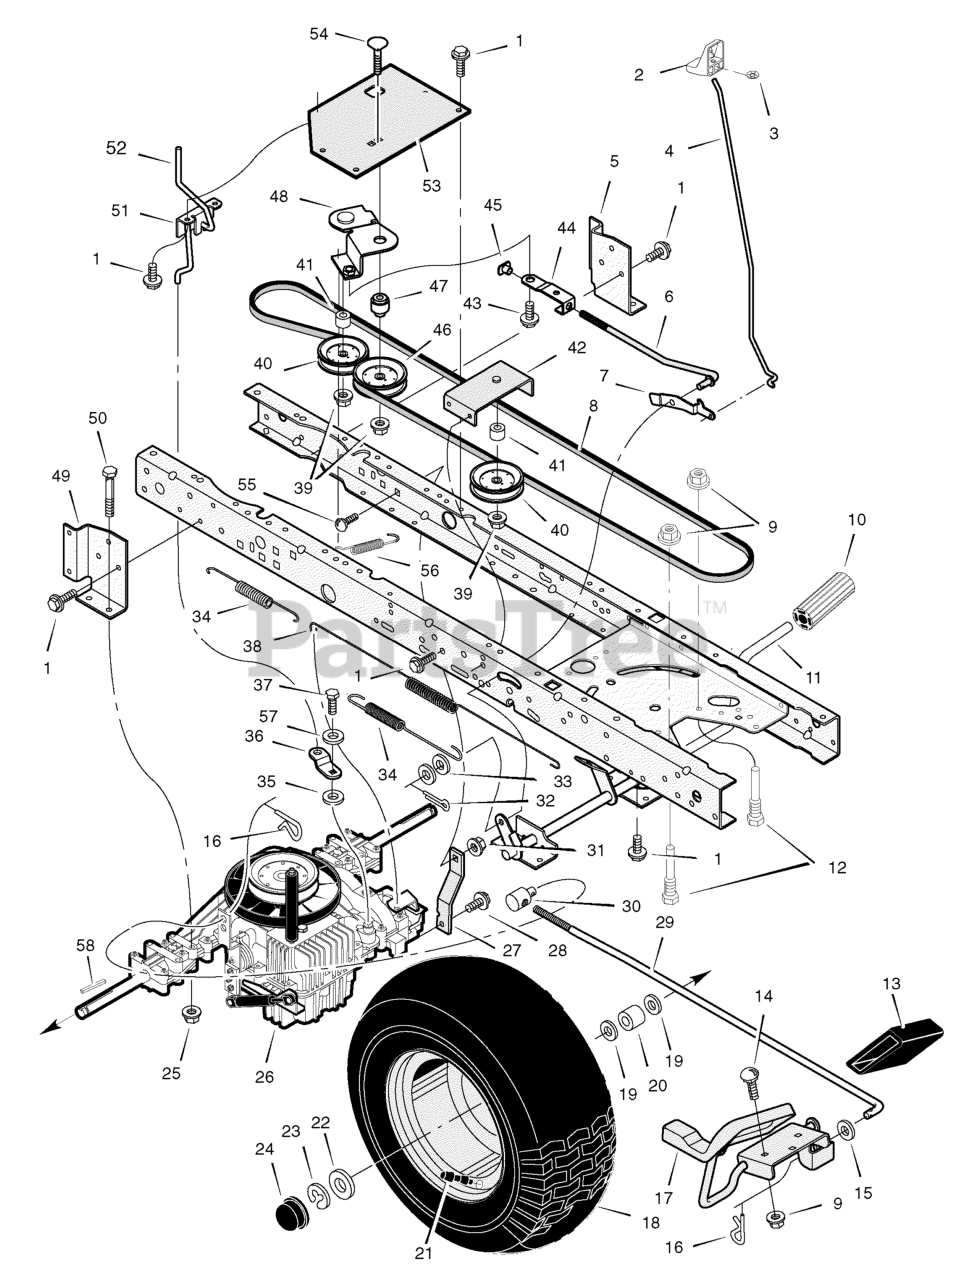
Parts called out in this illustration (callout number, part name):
1	Screw
2	Knob, Parking Brake
3	Nut, Push
4	Rod, Parking Brake
5	Bracket, Left Transaxle
6	Rod, Clutch
7	Latch, Parking Brake
8	V-Belt, Drive
9	Nut, Flange
10	Pedal, Brake/Clutch
11	Assembly, Brake Pedal
12	Screw, Guide
13	Pad, Pedal
14	Bolt, Carriage
15	Washer
16	Pin, Hair
17	Pedal Assembly, Hydro
18	Wheel & Tire Ass'y - 20"
19	Washer
20	Spacer
21	Stem, Valve
22	Washer
23	E-Ring
24	Cap, Hub
25	Nut, Centerlock
26	Transaxle
27	Strap, Torque
28	Screw
29	Rod, Control
30	NUT, Adjusting
31	Nut, Centerlock
32	Pin, Cotter
33	Washer
34	Spring, Extension
35	Washer
36	ARM, Disconnect
37	Capscrew
38	Spring, Brake
39	Locknut, Flange
40	Pulley, Idler
41	Spacer
42	Bracket, Idler Assembly
43	Bolt, Shoulder
44	Link, Clutch
45	Nut, Tee
46	Pulley, Idler
47	Bushing, Pivot
48	Arm Assembly, Idler
49	Bracket, Right Transaxle
50	Bolt, Hex
51	Bracket, Disconnect
52	Rod, Disconnect
53	Bracket, Idler Pivot
54	Bolt, Carriage
55	Bolt, Carriage
56	Spring, Clutch
57	Washer
58	Key, Square 3/16"
